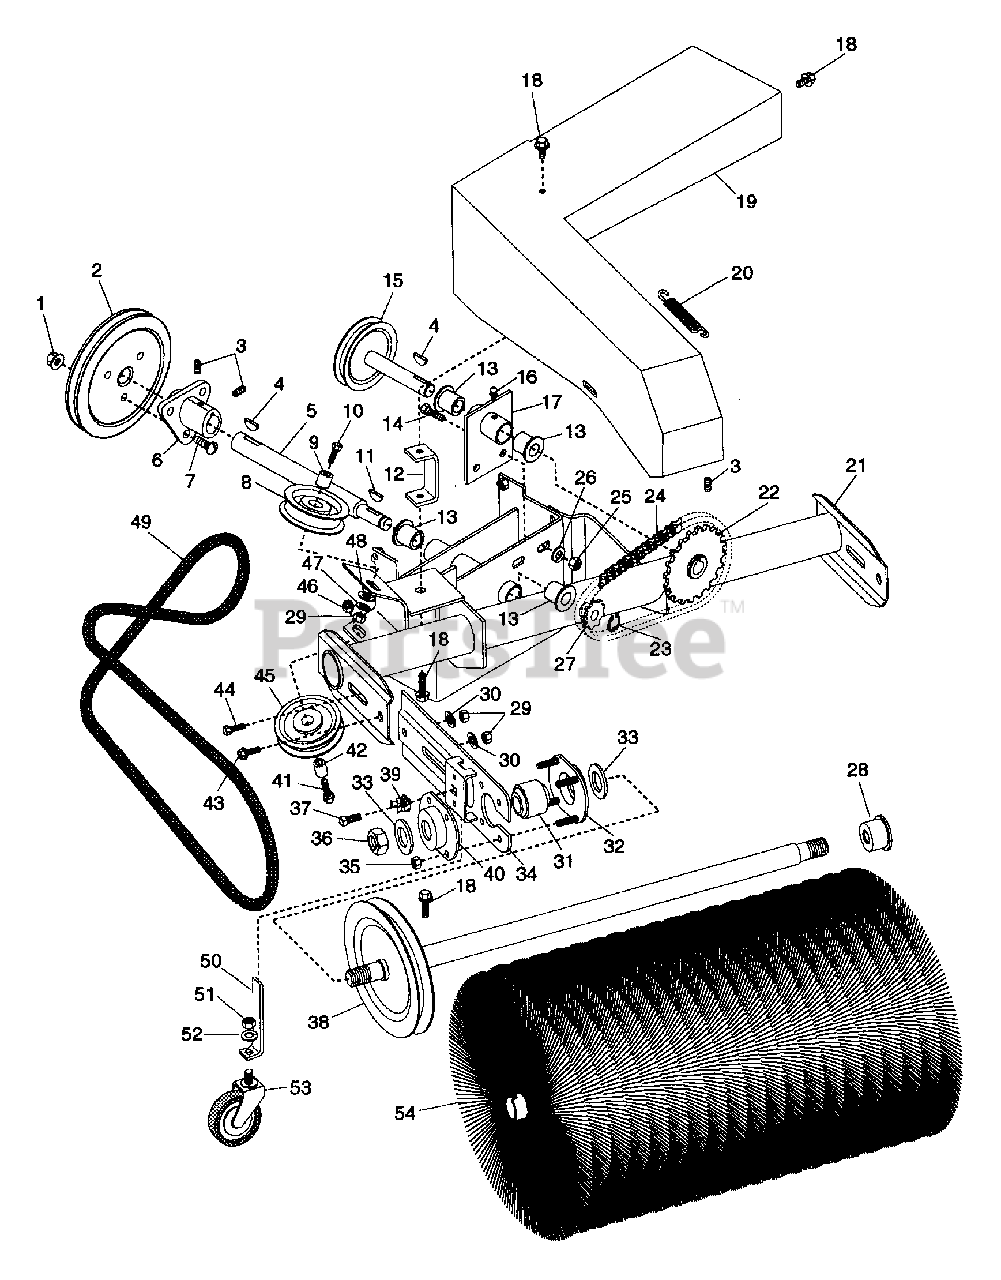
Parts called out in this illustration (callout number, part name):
1	NUT-FLG. .312-18 PL
2	PLY-V 8.50 X 1.25 3BLT
3	SCR-SET .32-18X.38 SKHCUPNL OH
4	KEY-WDRF .188X.75X.313 SAE 9
6	HUB
7	BLT-SERRDHD SL .31-18X.75 YZ
8	IDLER-FLAT 3.00 X .38 CLK.&CAP
9	SPACER .379X.625X.500
10	BLT-HEX .38-16X1.50 PL GR2
11	KEY-WDRF .125X.625X.250 SAE5
12	BRACKET
13	BSHG-FLG .750X1.000X.625X1.250
14	BLT-HEX .38-16X1.00 PL
15	SPINDLE
16	SPIN DRIVE ZERK FITTING
17	SPINDLE HOUSING
18	BLT-SERHFWH .31-18X.50 PL
19	BELT COVER
20	SG-TENS .048X.44X1.75 WLD 9
21	BRUSH FRAME
22	SPROCKET
23	RG-RTNG-EXT .500X.035
24	CHAIN
25	NUT-HEX .375-16
26	WSHR-LK .375X.115 HVY PL
27	9 TOOTH SPROCKET
29	NUT-HEX .312-18
30	WSHR-FL-STL .38X.875X.083 PL
31	BRG-BALL .500X1.38X.437
32	BEARING FLANGE
33	WSHR-FL-STL .531X1.062X.095 PL
34	ARM
35	NUT-LK DUAL FACE 10-24 PL
36	NUT-LK-CTR .50-20 PL
37	SCR-SET .38-16X.75 SQHCUP HT
38	BRUSH SHAFT
39	NUT-RETNR .38-16 TINRMAN
40	BEARING FLANGE
41	BLT-HEX .31-18X1.50 PL GR2
42	SPCR, BRG .315X.50X.688X.281
43	BLT-SERHFWH .31-18X.75 PL
44	BLT-HEX .31-18X.75 PL GR2
45	IDLER-V 3.50 X .50 CAPITOL
46	NUT-LK-CTR .375-16 GR A PL
47	WSHR-LK .312X.097 PL HVY
48	WSHR-FL-STL .38X.875X.083 PL
49	V-BELT, 4L-WRAPPED C-L2089
50	ADJUSTMENT LEG
51	NUT .50-13 PL
52	WSHR-LK .500X.151 HVY PL
